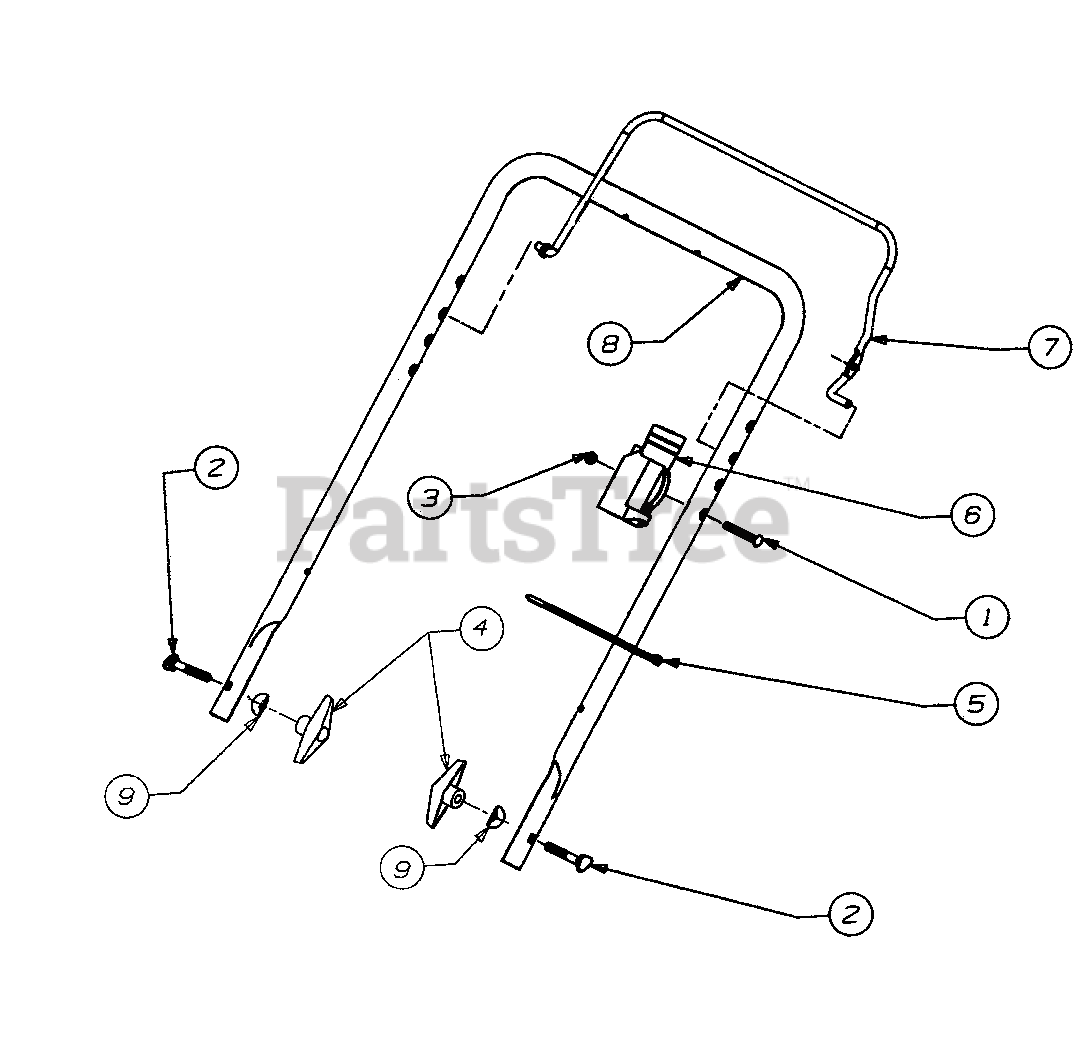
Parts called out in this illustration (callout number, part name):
1	Oval C-Sink L Screw
2	Bolt Carriage
3	Nut Insl. Lock
4	Knob-Handle
5	Tie Cable
6	Control Lever Body
